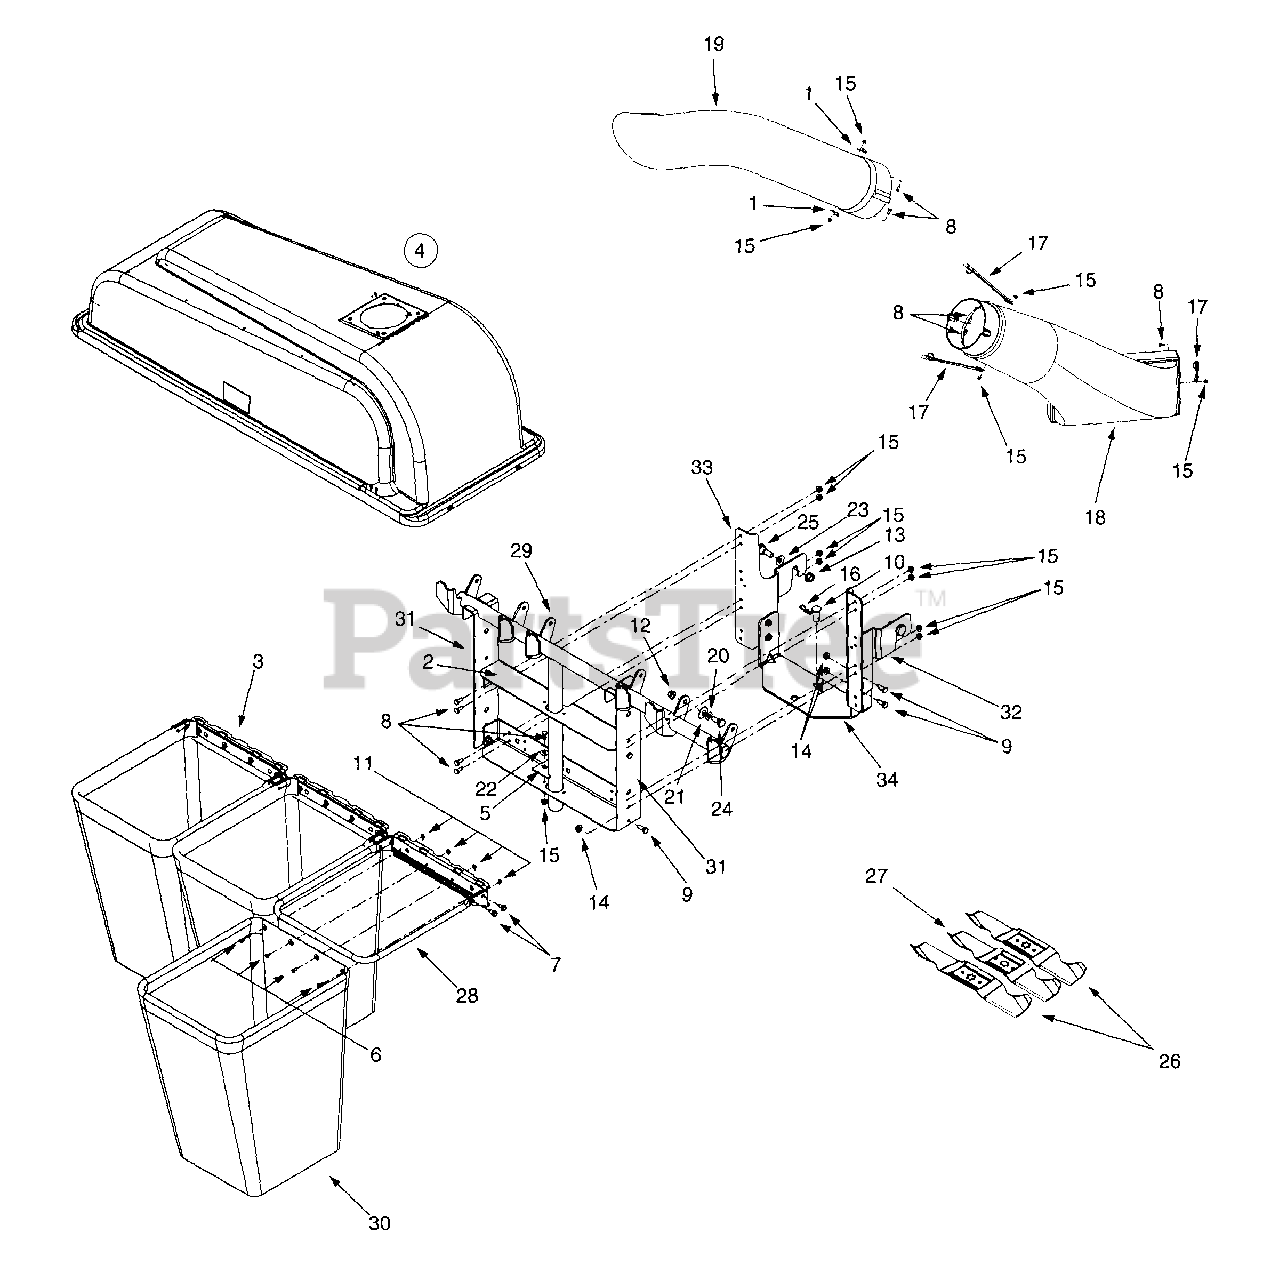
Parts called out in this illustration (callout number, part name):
1	Retainer Hook Bracket
4	Cover Assembly Complete
6	Screw, #10-24 x .5
7	Self Tapping Screw, 5/16-18 x .625
8	Hex Cap Screw, 1/4-20 x .62
9	Hex Cap Screw, 5/16-18 x .75
10	Clevis Pin
11	Hex Sems Nut, 10-24
12	Hex Flange Lock Nut, 3/8-16
13	Hex Flange Lock Nut, 7/16-20
14	Hex Flange Lock Nut, 5/16-18
15	Hex Flange Lock Nut, 1/4-20
16	Internal Cotter Pin, .148 x 3
17	Retainer Strap Assembly
18	Discharge Chute
19	Chute Tube
20	Flat Washer, .51 x .75 x .033
21	Bell Washer, .51 x 1.14 x .04
22	Bell Washer, .265 x .75 x .062
23	Bell Washer, .45 x 1.0 x .062
24	Shoulder Screw, .50 x .27, 3/8-16
25	Shoulder Screw, .625 x .5, 7/16-20
26	Star-center Blade, 16.28
27	Star-center Blade, 14.88
